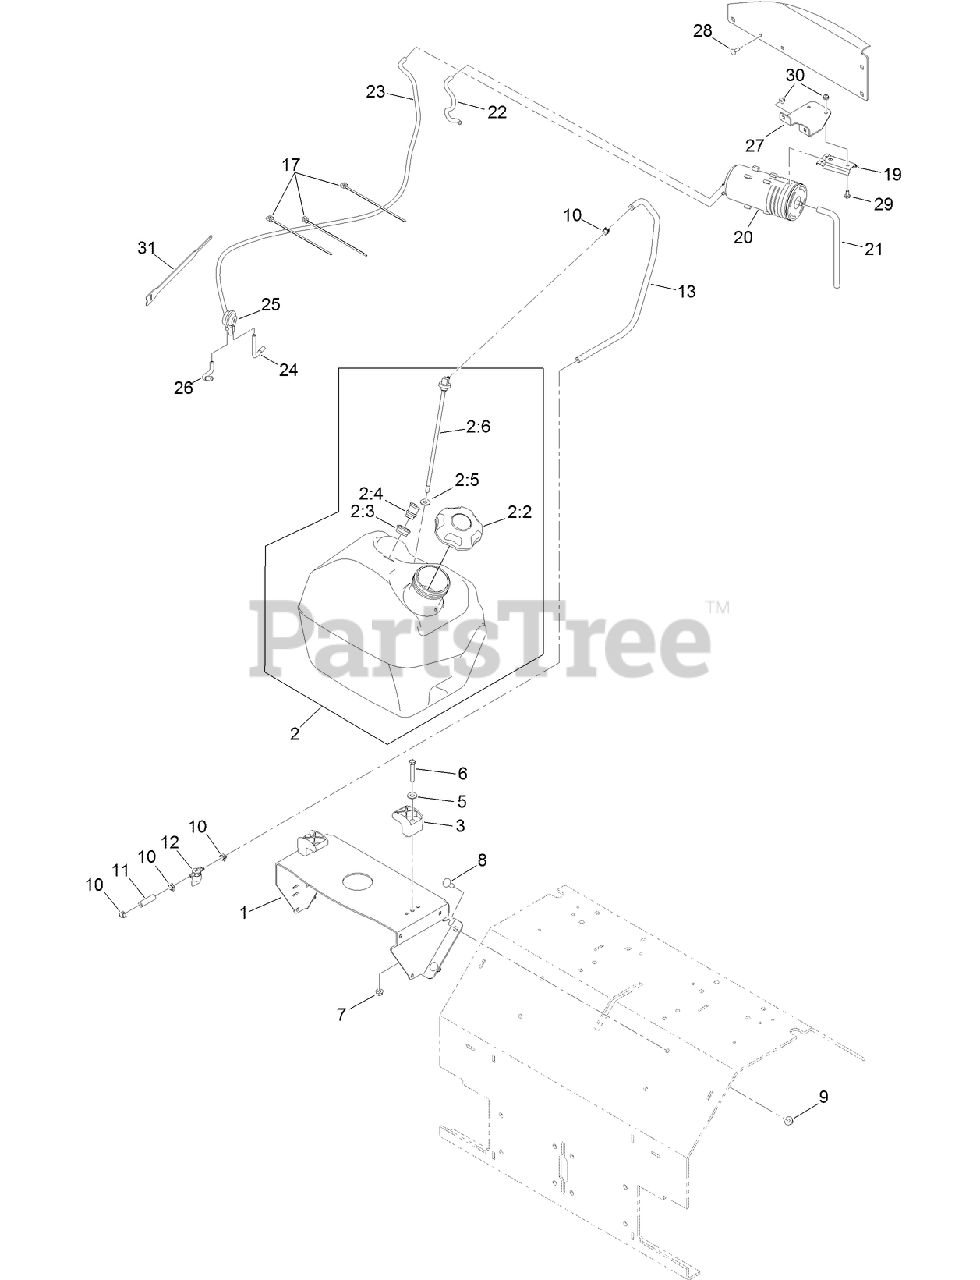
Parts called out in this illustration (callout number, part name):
1	SUPPORT-TANK, FUEL
2	FUEL TANK ASM
2:2	CAP-FUEL, RATCHETING
2:3	GROMMET
2:4	VALVE-VENT, FUEL
2:5	BUSHING
5	WASHER-FLAT
6	SCREW-HH
7	NUT-HF, NI
8	SCREW-CARR
9	NUT-HF, NI
10	CLAMP-HOSE
11	HOSE-FUEL
12	VALVE-FUEL
13	HOSE-LINE, GAS
17	TIE-CABLE
19	BRACKET-CANISTER, CARBON
20	CANISTER-CARBON, 800CC
21	HOSE-VENT, CANISTER
22	HOSE-EMISSIONS
23	HOSE-VENT, FORMED
24	HOSE-VENT, FORMED
25	VALVE-CONTROL, VACUUM
26	HOSE-VENT, FORMED
27	BRACKET-MOUNTING, CANISTER
28	BOLT-CARR
29	SCREW-HH
30	NUT-HF
31	STRAP-VELCRO, CABLE TIE
